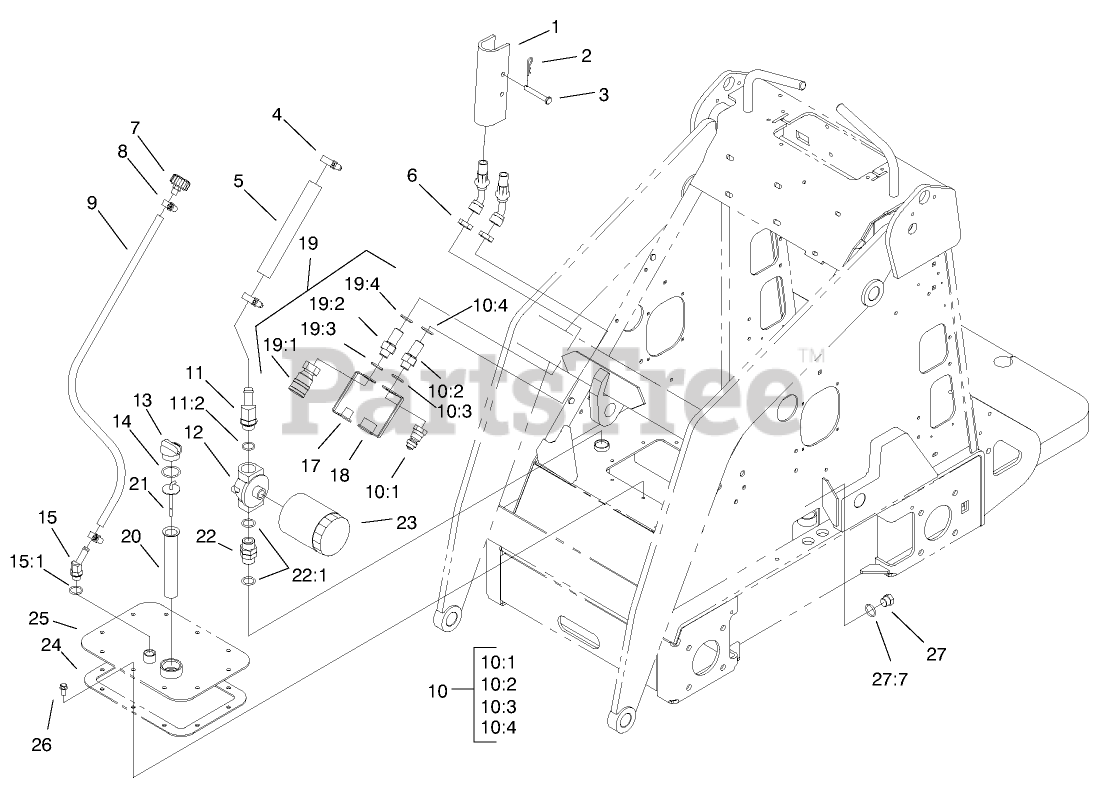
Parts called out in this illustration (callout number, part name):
1	LOCK-CYLINDER
2	PIN-HAIR
3	PIN-CLEVIS
4	CLAMP-HOSE
5	HOSE-SUCTION, HYD
6	NUT-LOCK, BULKHEAD
7	BREATHER
8	CLAMP-HOSE
9	HOSE-VENT
10	BULKHEAD NIPPLE ASM
10:1	NIPPLE-FACE, FLUSH
10:2	FITTING-ADAPTER, BULKHEAD
10:3	O-RING
10:4	O-RING
11	FITTING-45 DEG
11:2	O-RING
12	HEAD-FILTER
13	PLUG-PLASTIC
14	O-RING
15	FITTING-HYD, 45 DEG
15:1	O-RING
17	CAP-DUST, NIPPLE
18	CAP-DUST, COUPLER
19	BULKHEAD COUPLER ASM
19:1	COUPLER-FACE, FLUSH
19:2	FITTING-ADAPTER, BULKHEAD
19:3	O-RING
19:4	O-RING
20	FILTER-SCREEN
21	DIPSTICK-OIL
22	FITTING-THREAD, STRAIGHT
22:1	O-RING
23	FILTER-OIL, TRANSMISSION
24	GASKET-COVER
26	SCREW
27	PLUG-HEX
27:7	O-RING
